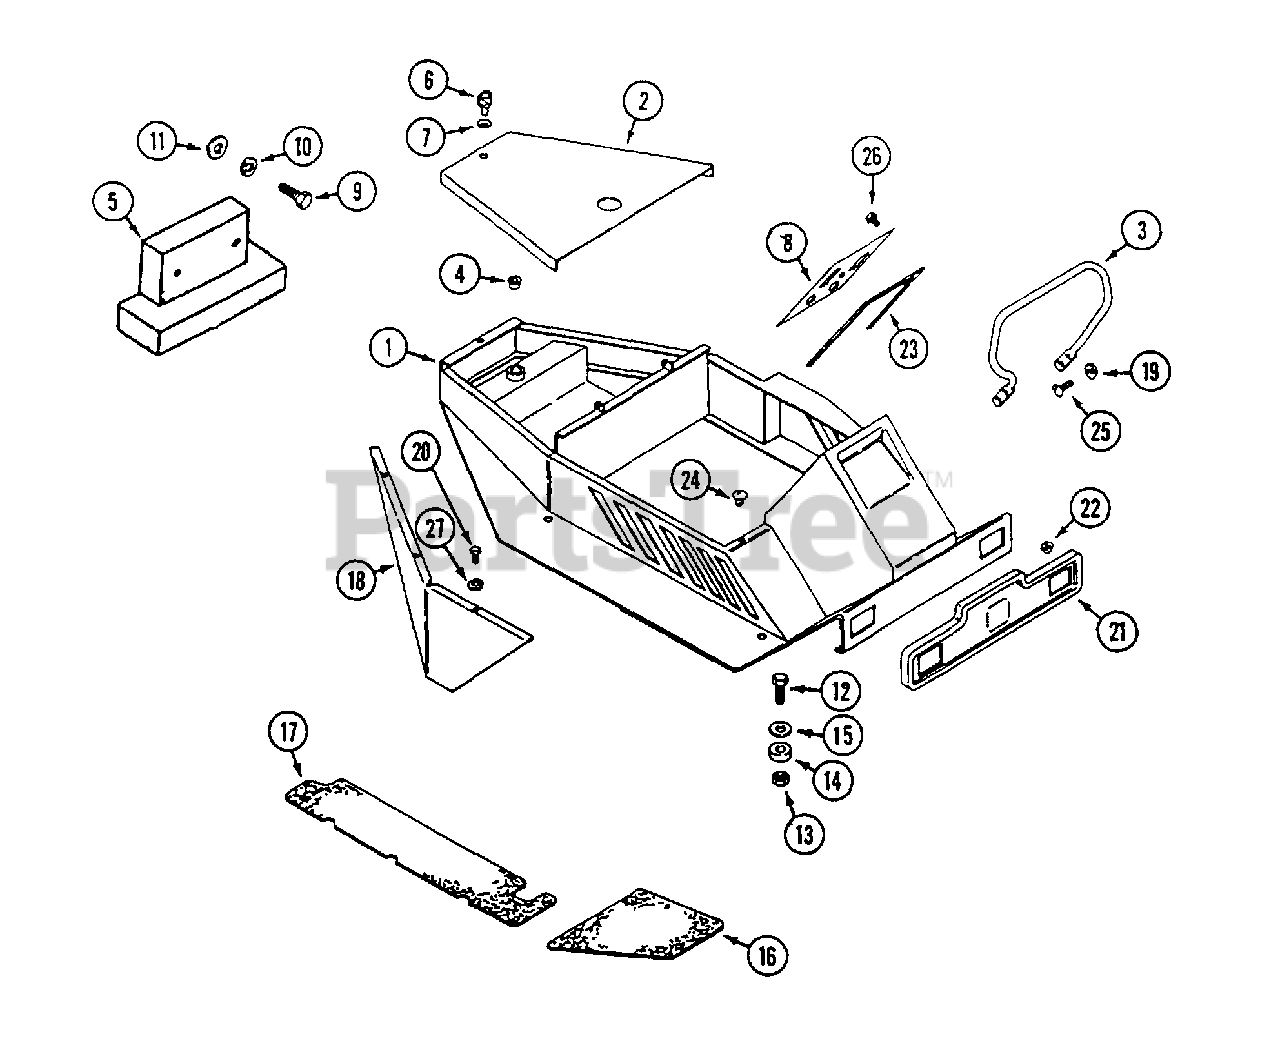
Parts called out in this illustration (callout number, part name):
1	BODY
4	BEARING - rear wheel fork
5	WEIGHT - tail
6	STUD - fastener
7	GROMMET - fastener
9	BOLT - 5/16" - 18 x 1"
10	LOCKWASHER - 5/16"
11	WASHER - 6/16"
12	BOLT - 1/2" - 13 x 3"
13	NUT - 1/2" lock
14	MOUNT - body, rubber
15	WASHER - mount, body
16	PAD - footrest, front L.H.
17	PAD - footrest, rear L.H.
19	NUT - 5/16" - 18 flange lock
20	BOLT - 1/4" - 20 x 3/4" self-tap
22	NUT - #8 - 32 flange lock
23	TRIM - 28"
24	BUMPER - nylon
25	BOLT - 5/16" - 18 x 3/4" carriage
26	SCREW - #12 x 1/2"
27	LOCKWASHER - 1/4"
